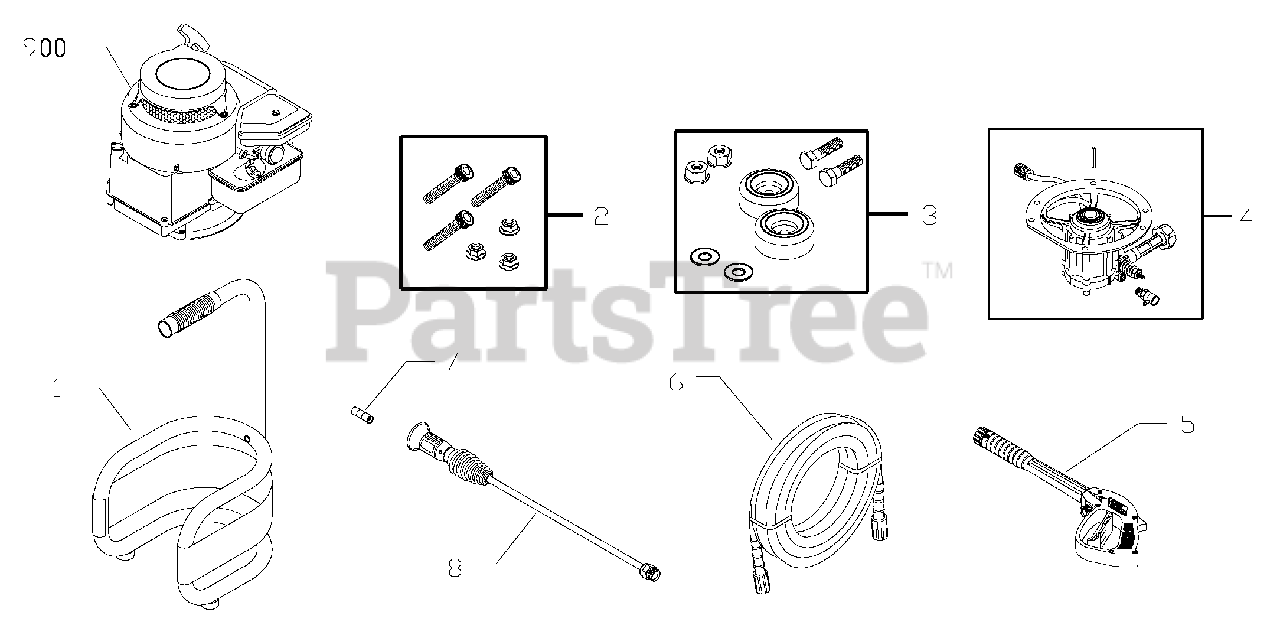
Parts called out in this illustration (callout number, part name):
2	KIT, Pump/Engine Mounting Hardware
3	KIT, Vibration Mount
5	GUN
6	HOSE, 25'
8	ASSY, Wand Hi - Lo
900	ENGINE
